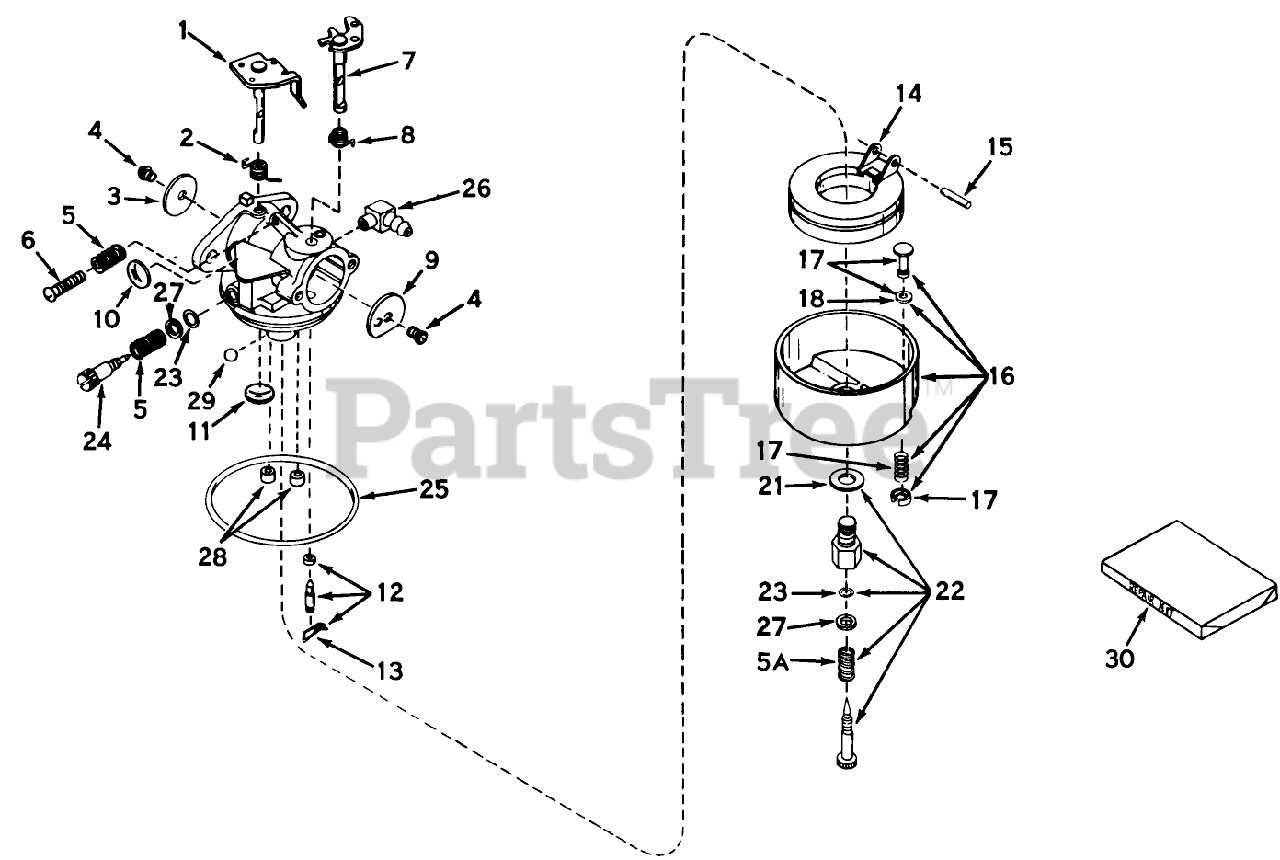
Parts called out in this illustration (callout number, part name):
1	Shaft Lever Assy.
2	Spring, Throtte Return
3	Shutter-Throttle
4	Screw-Shutter
5	Spring-Tension
5A	Spring
6	Screw-Throttle Crack Screw / Idle Speed
7	Shaft Lever Assy., Choke
8	Spring, Choke return
9	Shutter-Choke
10	Plug-Welch, Idle Mixture Well
11	Plug-Welch, Atmospheric Vent
12	Inlet Needle, Seat Clip Assy. (Incl. No. 13)
13	Clip-Spring
14	Float,Carburetor
15	Shaft-Float
16	Bowl Drain Assy., Float (Incl. No. 17)
17	Plunger Assy., Drain (Incl. Ref. 18)
18	Gasket-Plunger, Drain
19	Spring, Drain Plunger
20	Retainer, Plunger Spring
21	Washer-Bowl Nut
22	Adjustment Screw Assy., Main (Incl. Nos. 5A, 21 23)
23	ORing
24	Screw, Idle Adjustment
25	O Ring-Bowl, Float
26	Fitting Fuel Inlet
27	Washer
28	Plug, Cup
29	BalI, Steel
30	Repair Kit
